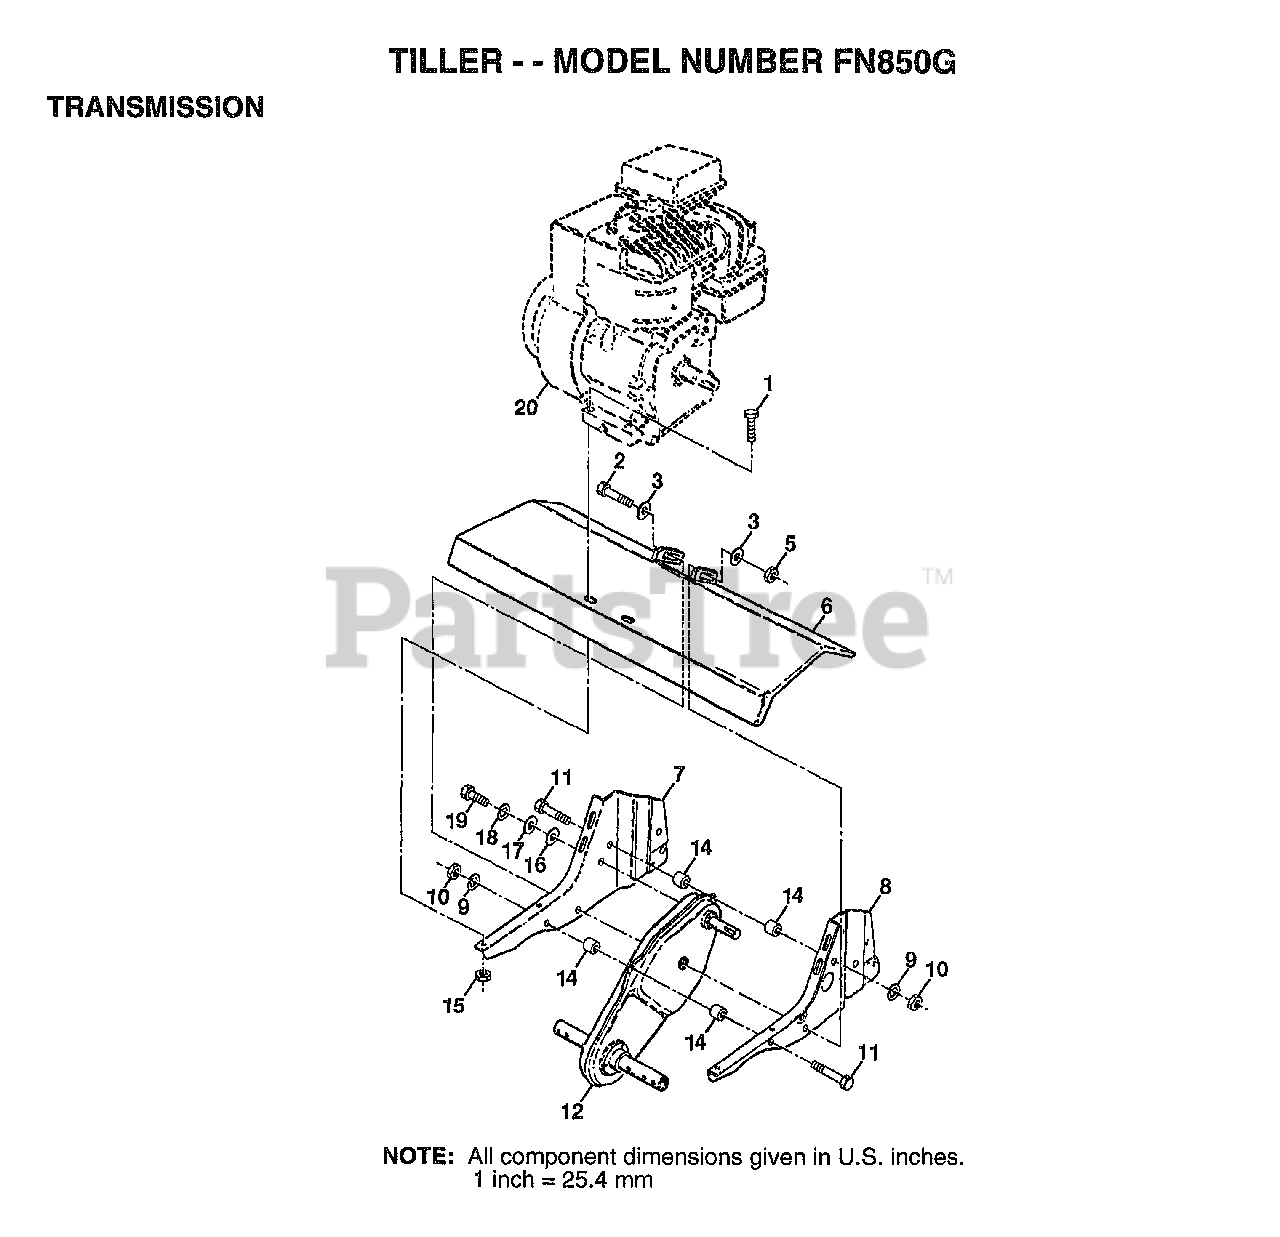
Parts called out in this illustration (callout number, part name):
1	BOLT.HEX.5/16-1.5
2	BOLT HEX 3/8-16
3	WASHER
5	NUT
6	"SHIELD, TINE"
8	ENGINE BRKT LH TI
9	LOCKWASHER
10	NUT.HEX.5/16-18
14	SPLIT SPACER RT
16	WASHER
17	WASHER
18	LOCKWASHER
19	BOLT
